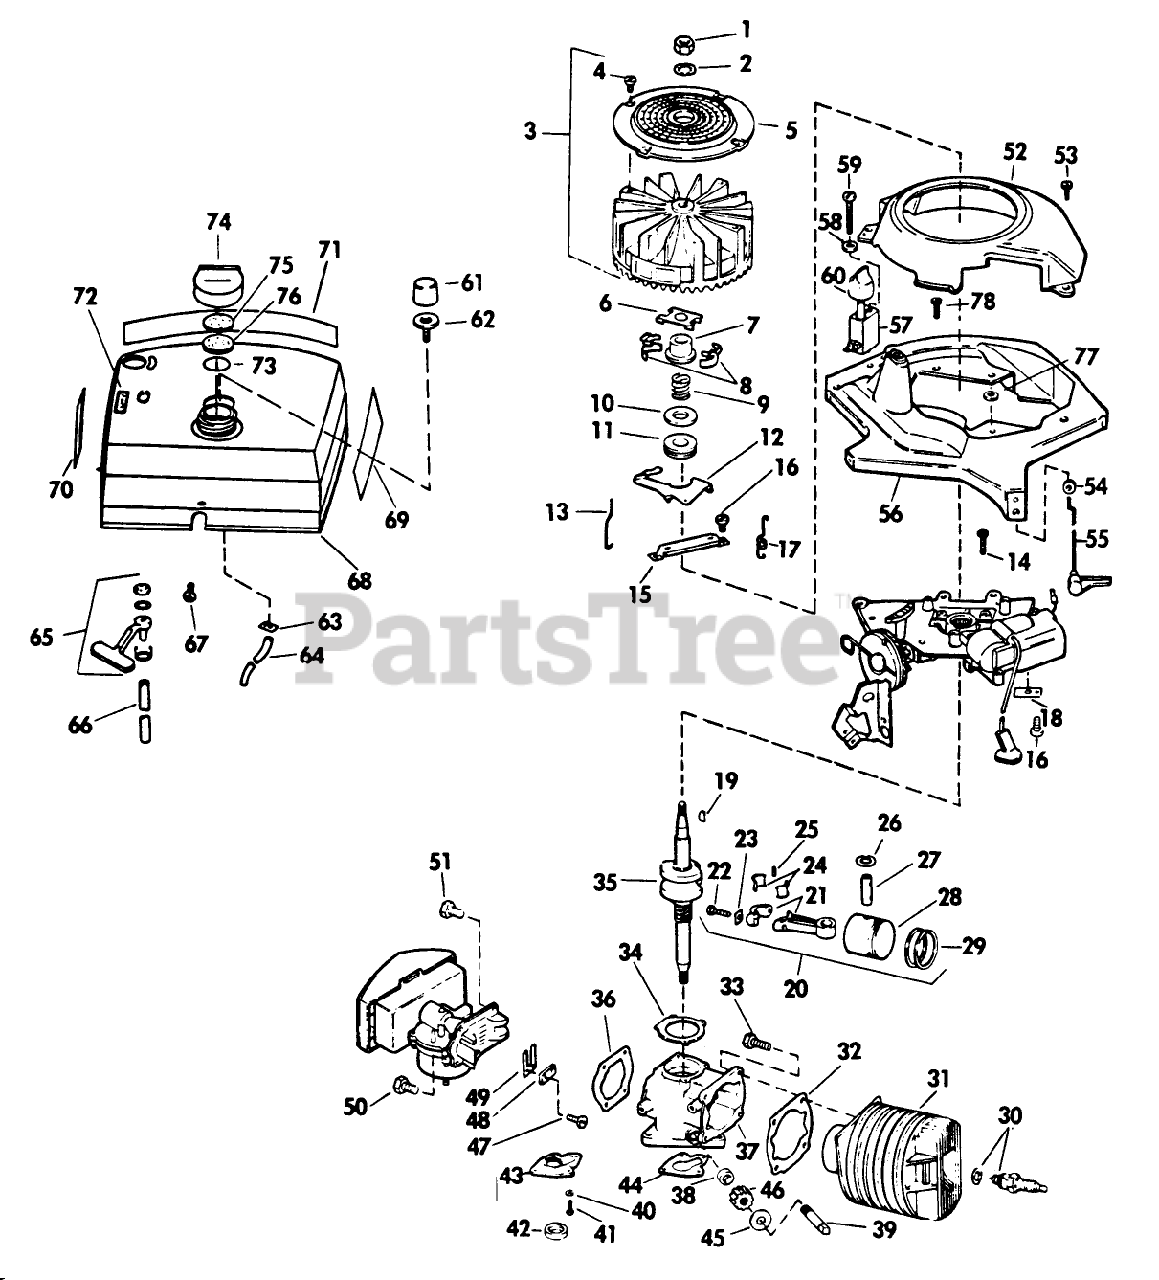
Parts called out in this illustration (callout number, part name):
1	NUT
4	SCREW F
6	YOKE S
7	COLLAR S
9	SPRING S
12	LEVER-GOVERNOR S
13	ROD
14	SCREW S
15	BRACKET
16	SCREW S
17	SPRING
18	TAB
19	KEY
22	SCREW
24	LINER ASM
26	RING-RETAINING
30	Spark Plug, Champion CJ-14 .035" Gap
32	GASKET S
34	GASKET S
36	GASKET S
38	SEAL S
41	SCREW
42	OIL SEAL
43	GEAR COVER S
44	GASKET-CVR S
45	THRUST WASHER
46	GEAR, DR SHAFT S
48	PLATE-BACKUP, REED
50	SCREW S
51	SCREW S
52	BAFFLE
53	SCREW S
55	GROMMET
58	WASHER S
60	KNOB
63	LOCKNUT S
64	TUBING S
67	SCREW S
75	GASKET S
76	BAFFLE - FOAM SM
78	SCREW S
